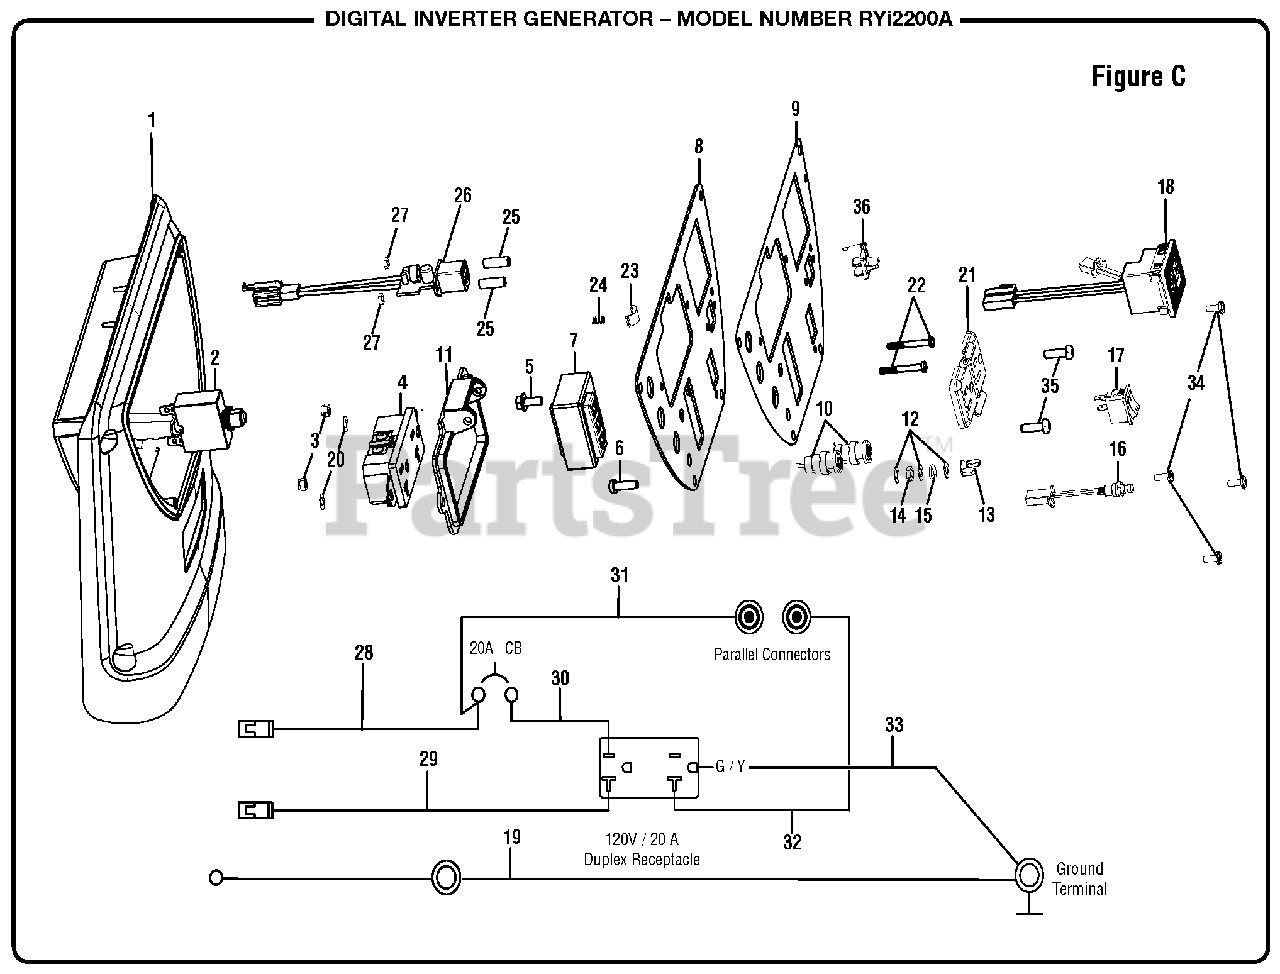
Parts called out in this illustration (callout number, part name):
1	Front Cover w/Labels & Foam
2	Circuit Breaker (20A)
3	Hex Nut (M4)
4	120 Volt Duplex Receptacle (20 Amp)
5	Bolt (M5 x 12 mm, Flange Hex Hd.)
6	Screw (M5 x 16 mm, Pan Hd.)
7	Ignition Module
8	Control Panel
9	Front Panel Label
10	Connector (Black)
11	Receptacle Cover (Back)
12	Washer (OD10 x ID5.3 x 0.5t)
13	Wing Nut (M5)
14	Hex Nut (M5)
15	Lock Washer (OD9 x ID5 x 1.3t)
16	Reset Button
17	Auto Idle Switch
18	12V DC Receptacle
19	Wire Lead (14AWG-220 mm, Yellow-Green)
20	Washer (OD10 x 4.2 x 1t)
21	Receptacle Cover (Front)
22	Screw (M3 x 25 mm, Pan Hd.)
24	Compression Spring
25	Spacer (17.2 mm)
26	Circuit Board (USB Port Charger)
27	Hex Nut (M3)
28	Wire Lead (14 AWG-220 mm)
29	Wire Lead (14 AWG-220 mm w/Dj441-4B)
30	Wire Lead (14 AWG-110 mm w/Dj441-4B)
31	Wire Lead (14AWG-80 mm)
32	Wire Lead (14AWG-110 mm w/Dj622-D6-3B)
33	Wire Lead (14AWG-120 mm)
34	Screw w/Washer (M4 x 10 mm, T20 Torx Button Hd.)
35	Screw (M4 x 14 mm, Pan Hd.)
36	USB Cover
